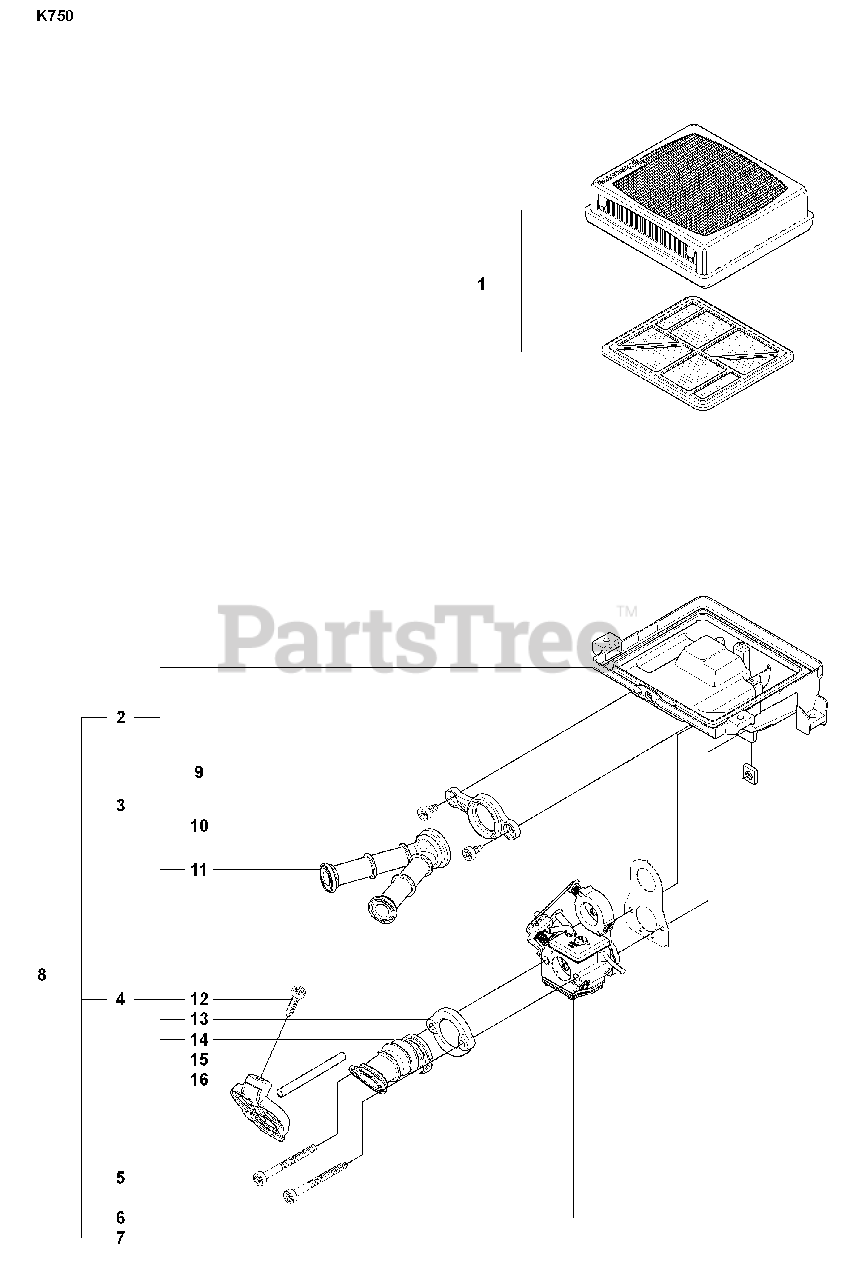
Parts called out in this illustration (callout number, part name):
2	CARBURETTOR BRACKET
4	INLET PIPE
6	CARBURETTOR
7	GASKET CARBURETTOR
8	CARBURETTOR BRACKET
10	FLANGE INLET PIPE
11	INLET PIPE
13	FLANGE INLET PIPE
14	INLET PIPE
15	IMPULSE HOSE
16	PLATE
